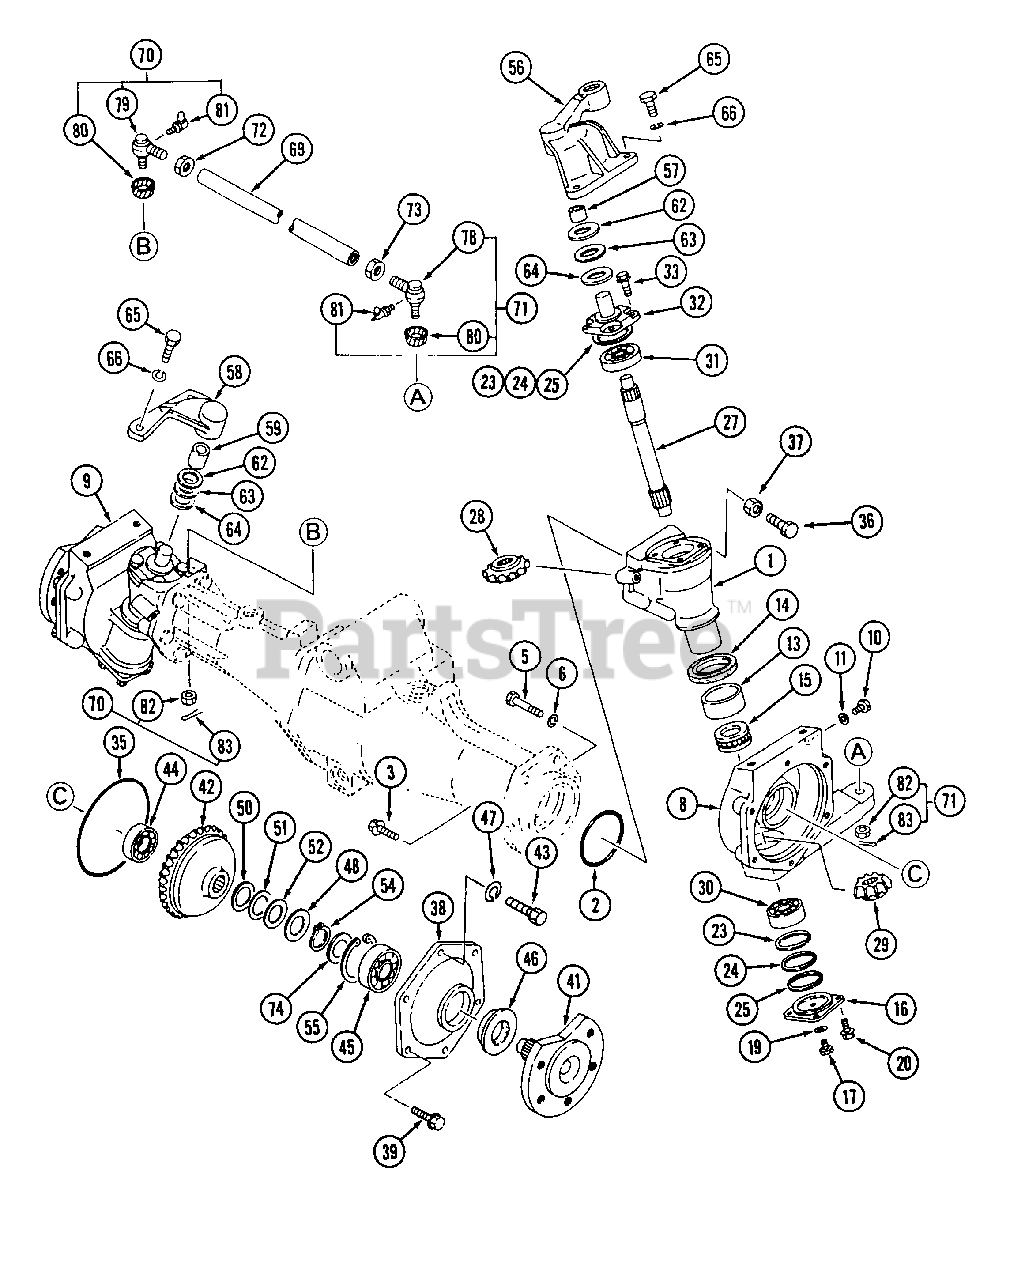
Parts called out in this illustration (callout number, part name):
1	Case, Kingpin
8	Case Final L.H.
9	Case Final R.H.
56	Knuckle Arm L.H.
58	Knuckle Arm R.H.
62	Liner, Thrust C t=1.4
63	Liner, Thrust D t=1.2
64	Liner, Thrust E t=0.8
70	End Ass'y. - Tie Rod R.H. Side (L.H. Thread)
71	End Ass'y. - Tie Rod L.H. Side (R.H. Thread)
72	Nut (L.H. Thread) M17
73	Nut (R.H. Thread) M17
80	Cover, Dust
81	Nipple, Grease
